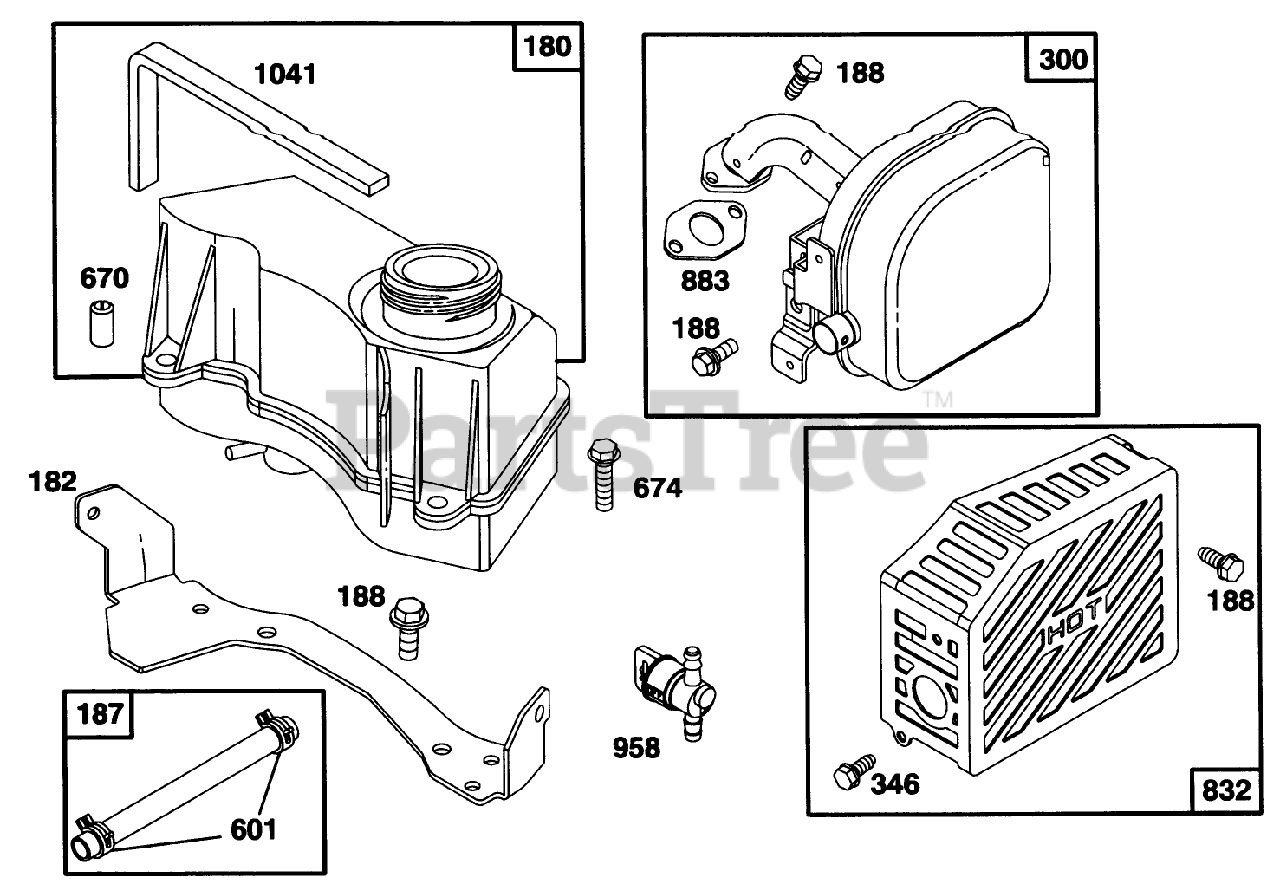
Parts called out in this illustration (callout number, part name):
180	TANK ASSY - FUEL
187	BRIGGS 296004
188	SCREW - HEX HEAD
300	MUFFLER - EXHAUST
670	SPACER
674	SCREW - HEX HEAD
